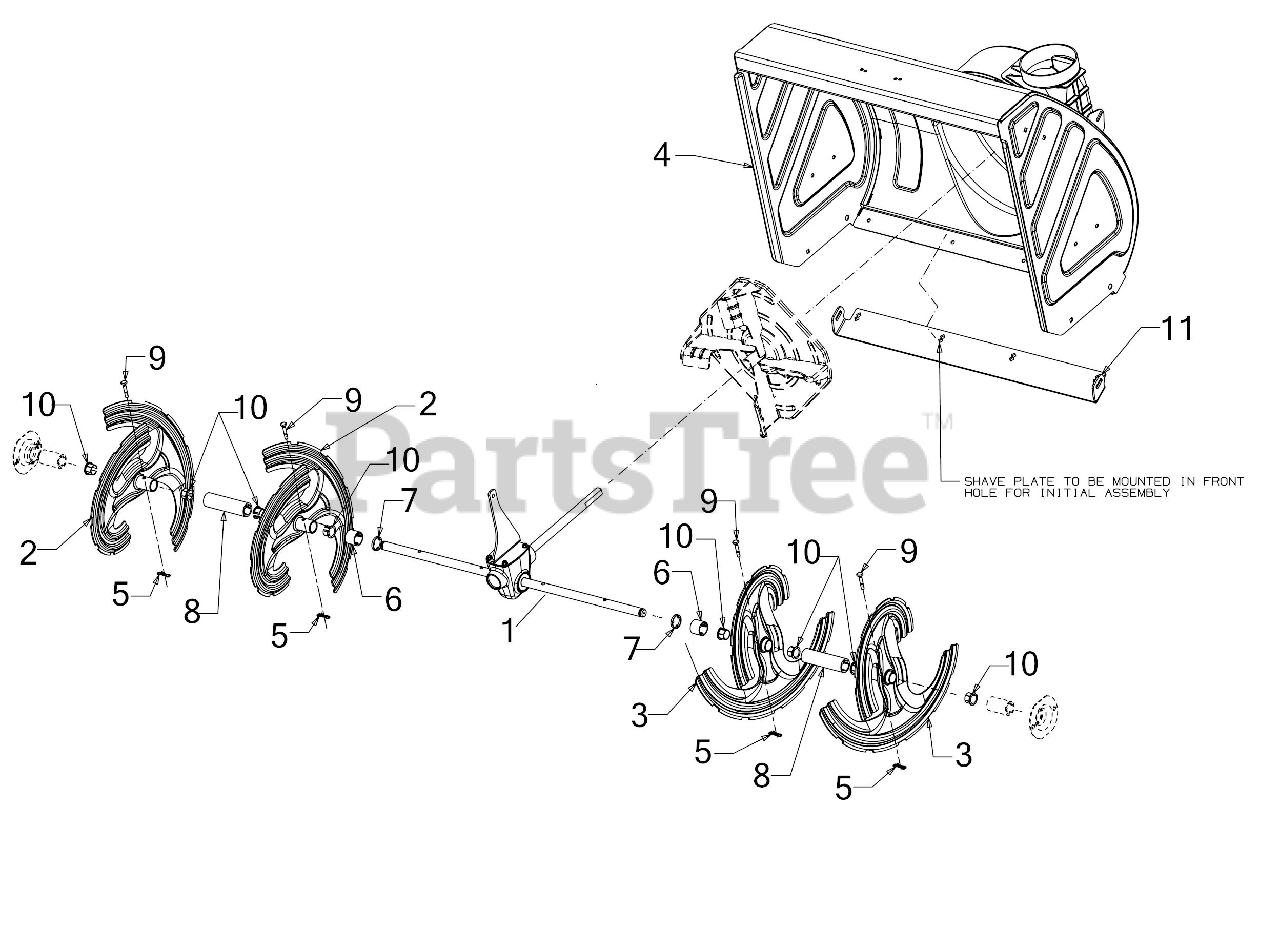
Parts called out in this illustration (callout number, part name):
1	30" AUGER GEARBOX ASSEMBLY
5	BOW TIE COTTER PIN 1/4-5/16
6	SPACER 1.25OD x .75ID X1.00 LG
7	SPCR 1.25 OD x 75IDX2.00LG
8	SPACER 1.25OD X .75ID X 4.470 LG
9	SHEAR PIN .25 x 1.50 GR2
10	FLANGE BUSHING
